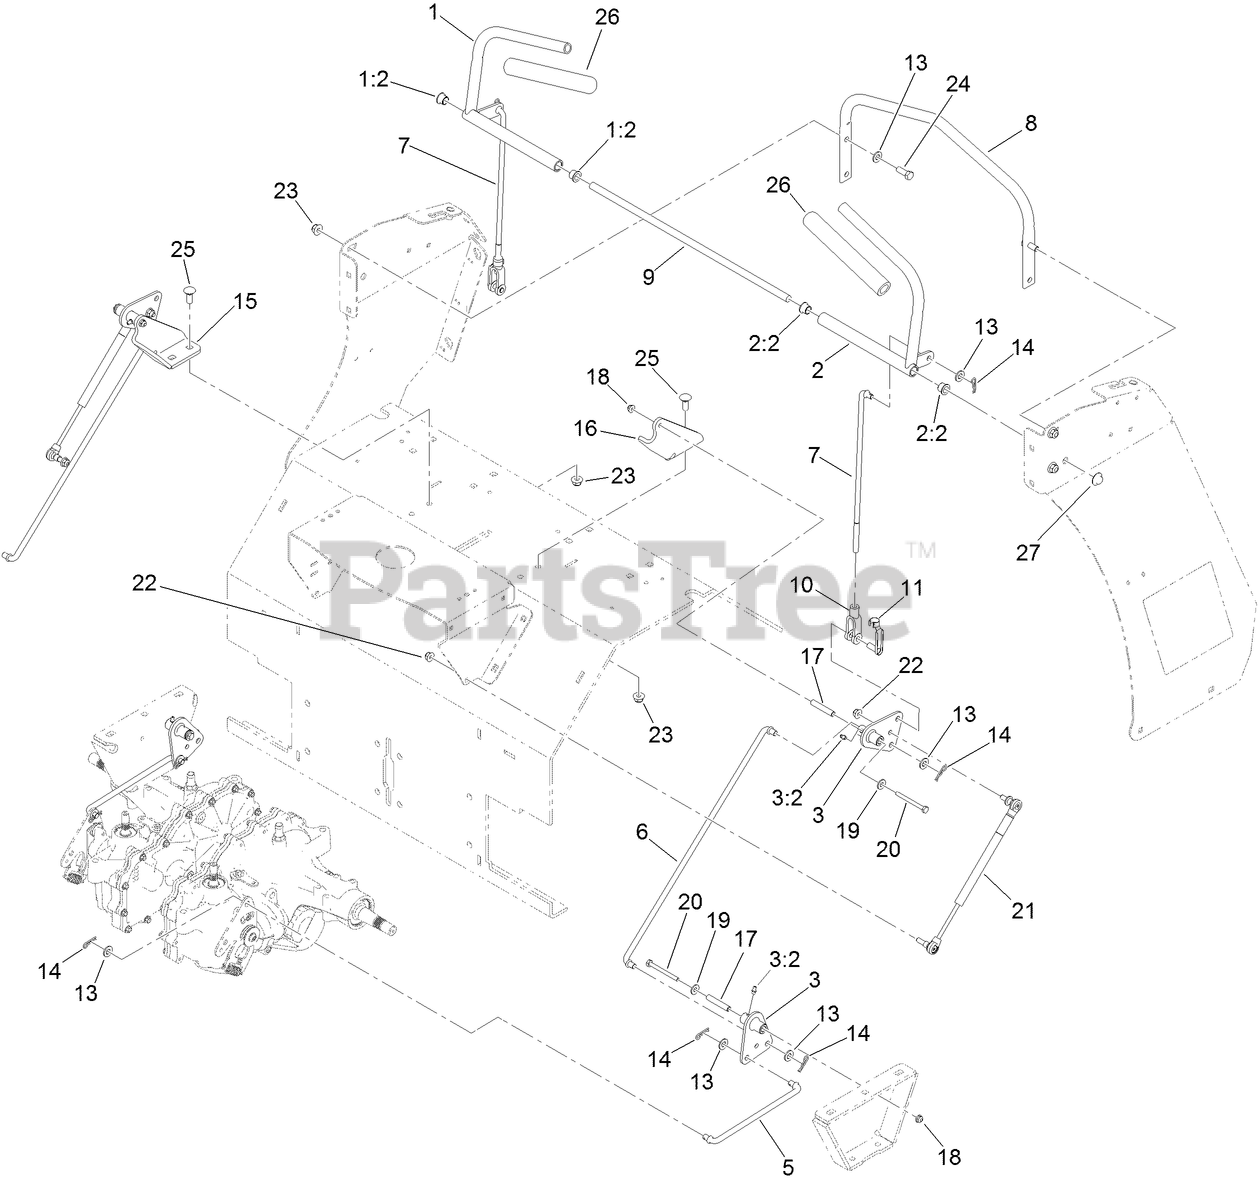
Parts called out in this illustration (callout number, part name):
1	RH CONTROL HANDLE ASM
1:2	BEARING-FLANGE
2	LH CONTROL HANDLE ASM
2:2	BEARING-FLANGE
3	CRANK-BELL
3:2	FITTING-GREASE
5	LINK-CONTROL, HYDRO
6	LINK-CONTROL, BELL CRANK
7	LINK-CONTROL, BELL CRANK
8	BAR-REFERENCE
9	SHAFT-PIVOT, CONTROL
10	YOKE-LINKAGE, BRAKE
11	Pin-Spring, Clevis
13	WASHER-FLAT
14	PIN-COTTER
15	BRACKET-PIVOT, RH
16	BRACKET-PIVOT, LH
17	SPACER
18	NUT-HF
19	WASHER-FLAT
20	SCREW-HH
21	DAMPER-CONTROL, MOTION
22	NUT-HF, NI
23	NUT-HF, NI
24	SCREW-HH
25	BOLT-CARR
26	GRIP-LEVER, CONTROL
27	NUT-PUSH
